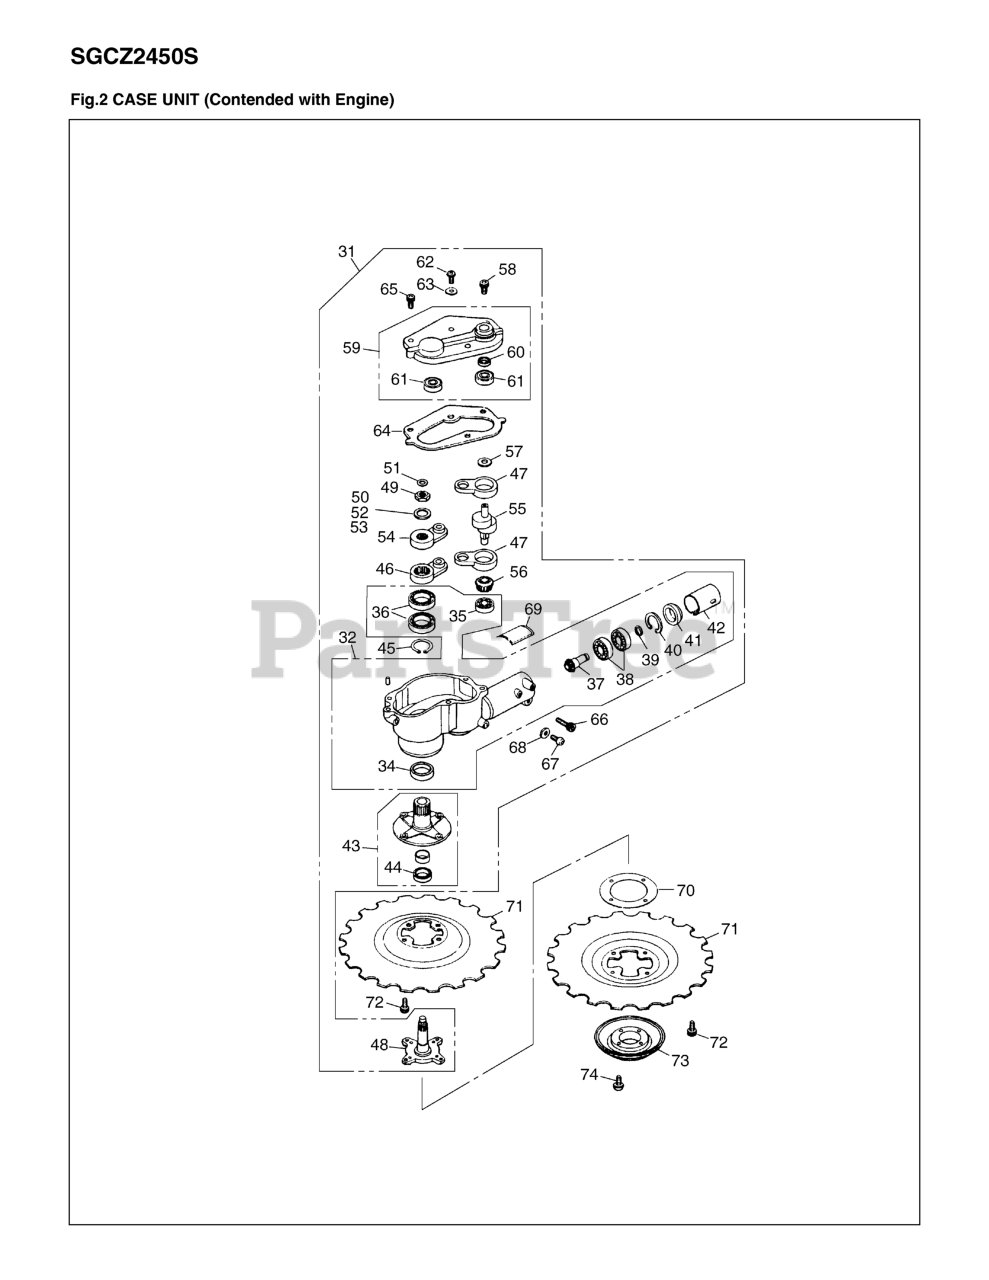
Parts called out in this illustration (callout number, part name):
31	CUTTERCASE ASSEMBLY
32	CUTTERCASE (RPLS -98100)
34	SEAL, OIL
36	BEARING
37	PINION
38	BEARING (RPLS T3403-13510)
39	RING, SNAP
40	RING, SNAP, M26 X 1.2
41	PACKING
42	SPACER (RPLS -13950)
43	SHAFT, OUTER-C
44	SEAL, OIL
45	RING, SNAP, M20 x 1.2
46	ARM, LOWER (RPLS -13411)
47	CONROD (RPLS 3805-13432)
48	SHAFT, INNER
50	SHIM, 0.3t
52	SHIM, 0.2T
53	SHIM, 0.1t
54	ARM, UPPER (RPLS -13611)
55	CRANKSHAFT (RPLS -13710)
56	GEAR
57	WASHER, M8 x 1.2
58	BOLT
59	COVER COMP
60	SEAL, OIL
62	SCREW, M6 x 10
63	WASHER, M6 x .8
64	GASKET
65	BOLT, M5 x 20
66	BOLT, M6 x 1.35
67	SCREW, M5 x 14
68	WASHER, M5x.8(RPLS 01624-20508
69	LABEL, CAUTION
71	BLADE
72	BOLT, M6 x 8
73	STABILIZER (RPLS -15151)
74	SCREW, M5 X 8
